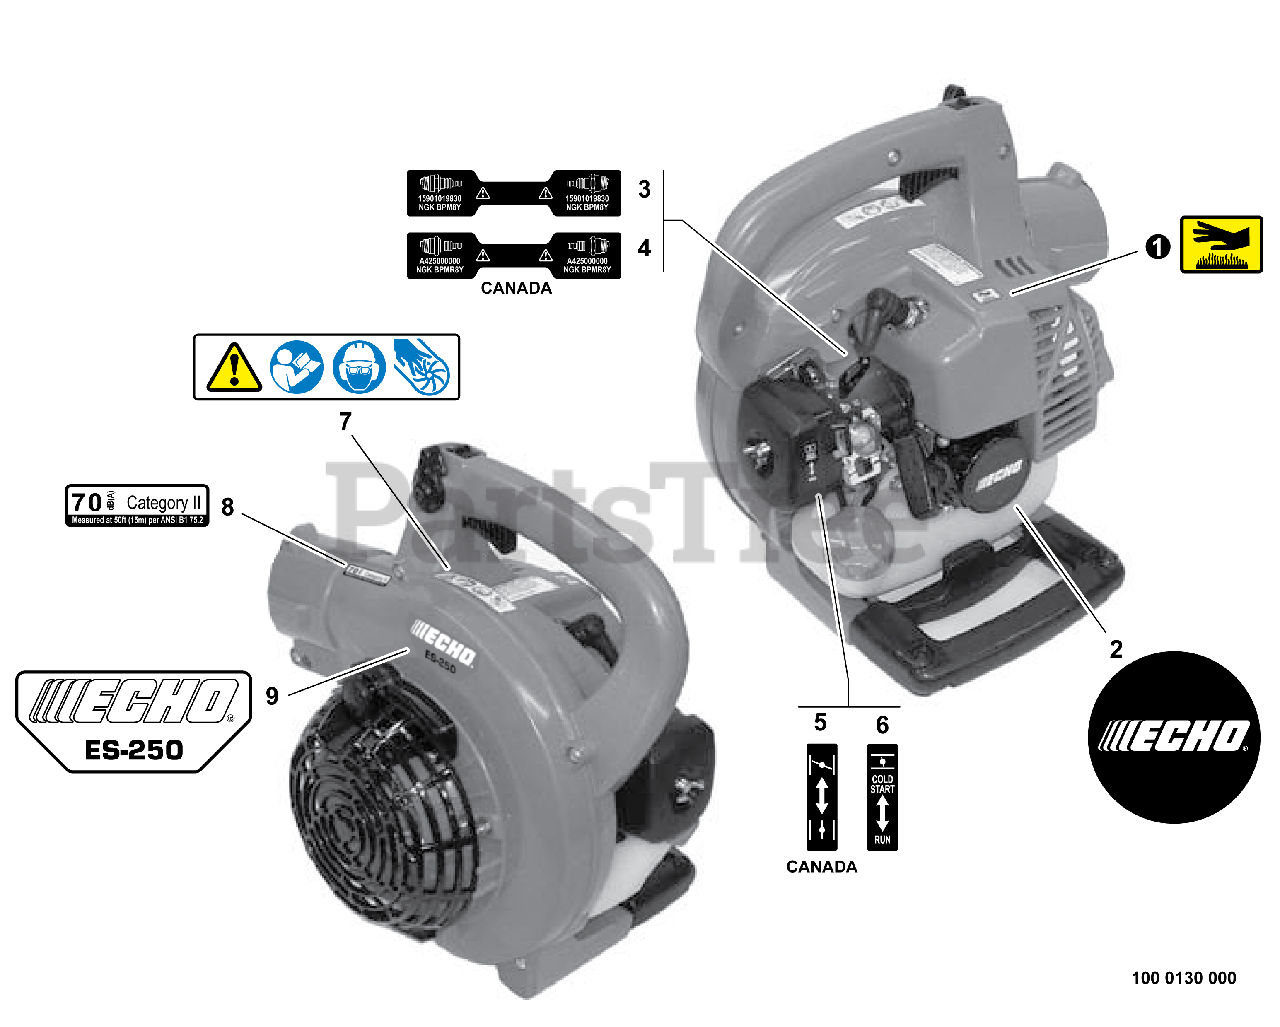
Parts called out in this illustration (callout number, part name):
1	LABEL - HOT SURFACE
2	LABEL - ECHO
3	LABEL - SPARK PLUG -- BPM-8Y
4	LABEL - SPARK PLUG -- BPMR-8Y
5	LABEL - CHOKE
6	LABEL - CHOKE
7	LABEL - CAUTION
8	LABEL - NOISE 70dB(A) CAT II
9	LABEL - MODEL ES-250
